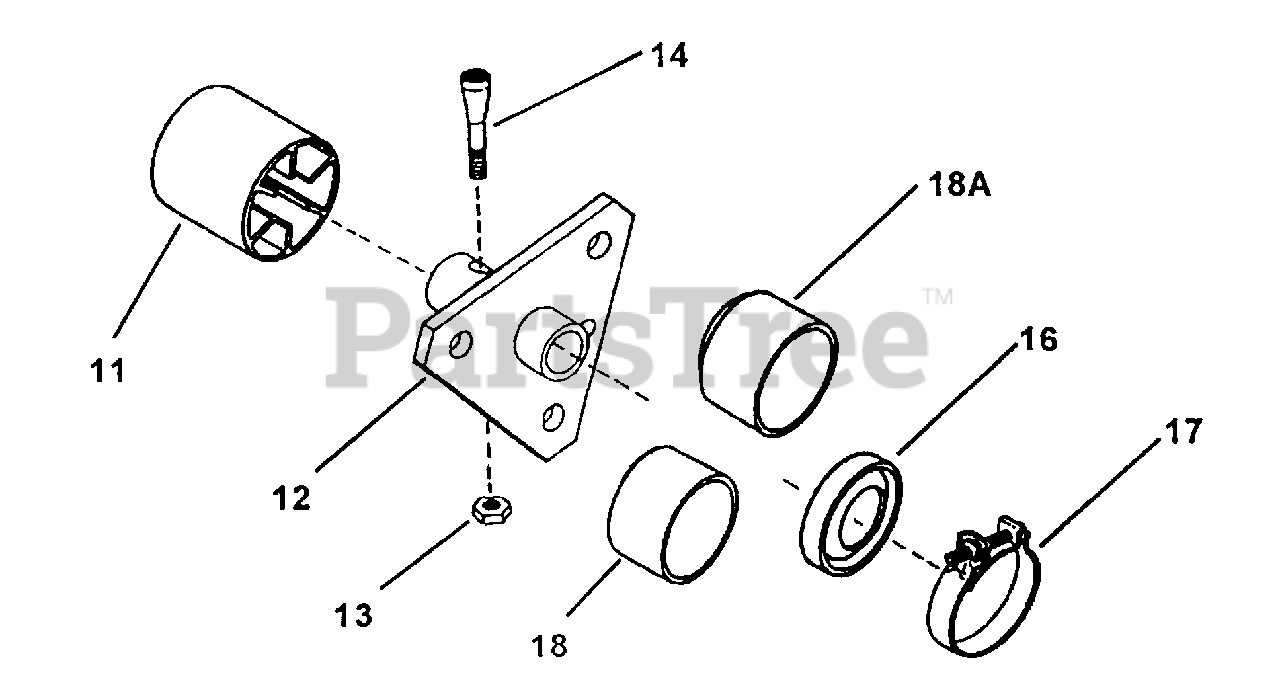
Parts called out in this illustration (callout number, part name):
11	CAP, Hub
12	HUB, Wheel LH, 3 Hole 3/4" ID
13	NUT, 5/16-24 Hex Center Lock
14	BOLT, 5/16-24 x 1-5/8" Tapered
16	SEAL, OIL .750" ID x 1.832" OD
17	CLAMP, Boot, 2"
18	BOOT, LH Ball Bearing Models 3/4"
18A	BOOT, Standard Models 3/4"
